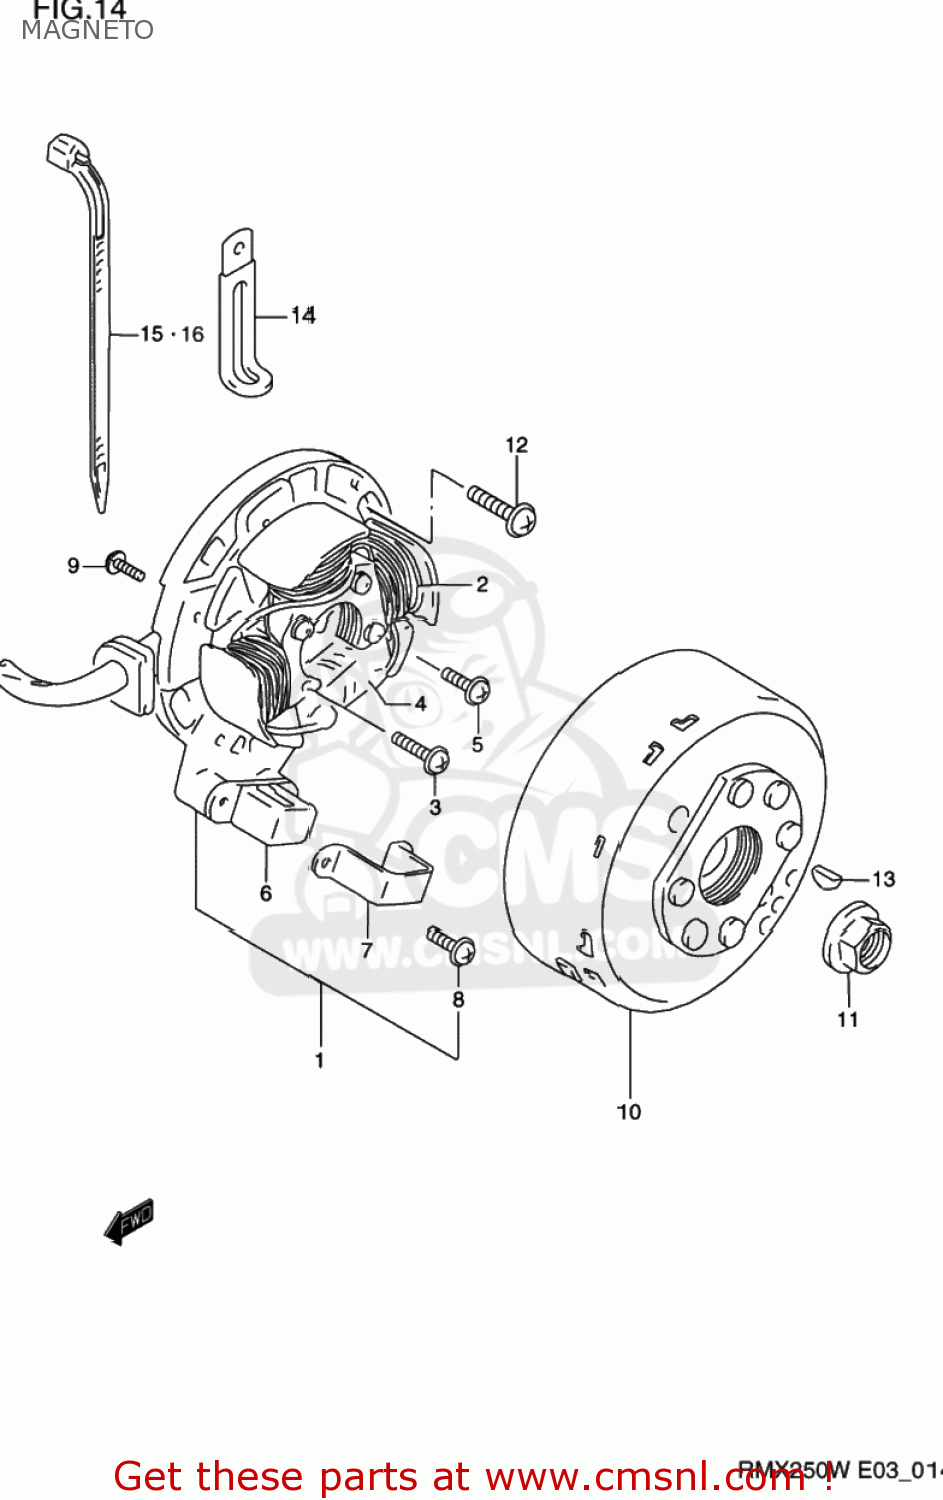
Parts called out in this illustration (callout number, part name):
1	STARTER ASSY
2	COIL,LIGHTING
3	SCREW
4	COIL,PRIMARY
5	SCREW
6	COIL,PULSER
7	HOLDER,PICK UP COIL
8	SCREW
9	SCREW
10	ROTOR ASSY
11	NUT
12	SCREW
13	KEY
14	CLAMP(L:65)
15	CLAMP(L:125)
16	CLAMP(L:235)
